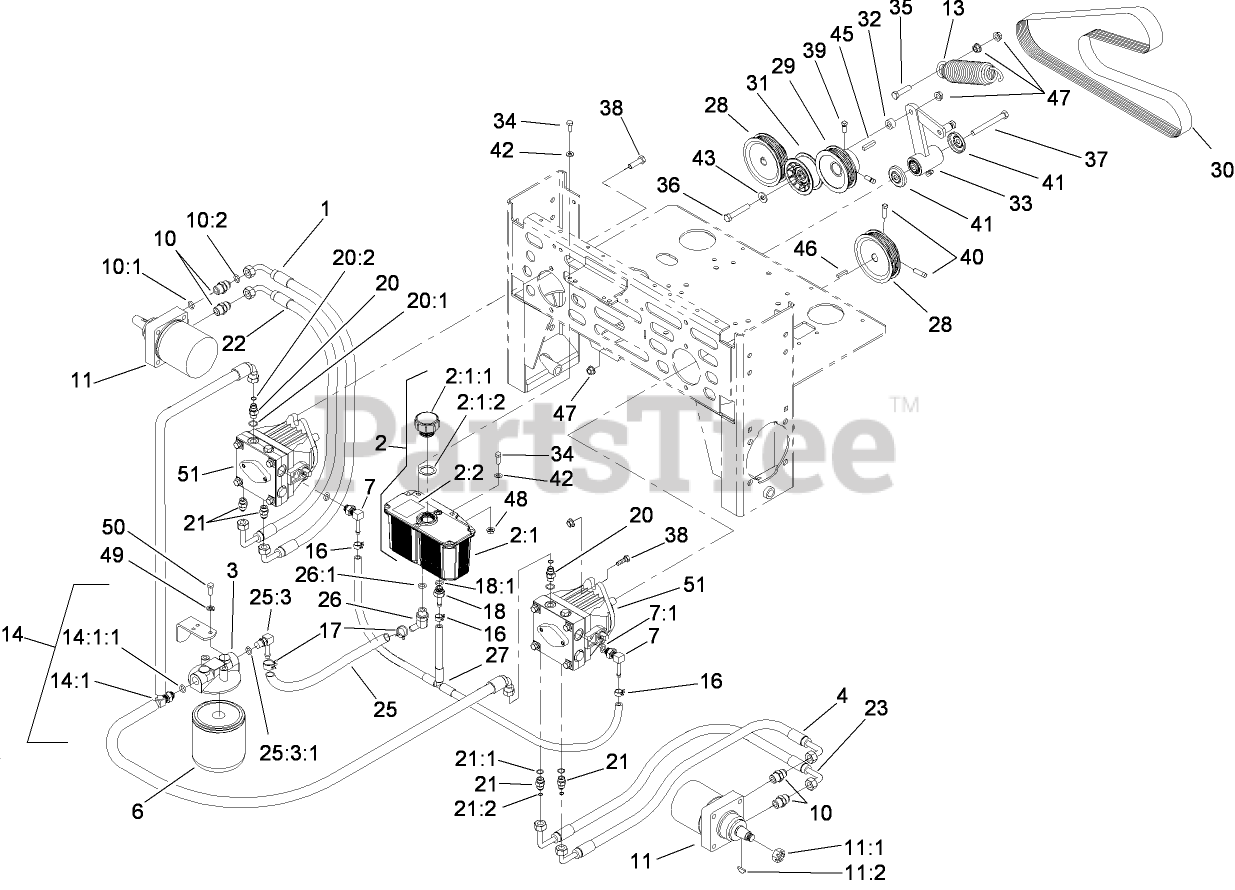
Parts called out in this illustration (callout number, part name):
1	HYD HOSE ASM
2	HYD Reservoir ASM
2:1	Reservoir-HYD
2:1:1	CAP-RESERVOIR, HYD
2:1:2	GASKET-CAP
2:2	DECAL-TANK, HYD
3	HEAD-FILTER
4	HYD HOSE ASM
6	FILTER-OIL, HYD (WINTER)
6	FILTER-OIL, HYD
7	ELBOW-90 DEG
7:1	O-RING
10	Fitting-Straight
10:1	O-RING
10:2	O-Ring
11	MOTOR-WHEEL
11:1	NUT-HH
11:2	KEY-WOODRUFF
13	Spring-Extension
14	HYD HOSE ASM
14:1	ADAPTER-RUN, TEE
14:1:1	O-RING
16	Clamp-Hose
17	Clamp-Hose
18	Adapter-Straight
18:1	O-RING
20	FITTING-STRAIGHT
20:1	O-Ring
20:2	O-RING
21	FITTING-STRAIGHT
21:1	O-RING
21:2	O-Ring
22	HYD HOSE ASM
23	HYD HOSE ASM
25	HYD HOSE ASM
25:3	FITTING-BARB
25:3:1	O-RING
26	FITTING-BARBED, 45 DEG
26:1	O-RING
27	HYD Hose ASM
28	SHEAVE
29	SHEAVE
31	PULLEY-FLAT IDLER
32	SPACER
33	PUMP IDLER ASM
34	SCREW-HH
35	SCREW-HH
36	SCREW-HH
37	SCREW-HH
38	SCREW-HH
39	SCREW-SET
40	SCREW-SET
41	GUARD-TOP
42	WASHER-FLAT
43	WASHER-FLAT
45	KEY-SQUARE
46	KEY-SQUARE
47	NUT-HHF, WHIZ
48	NUT-HF
49	WASHER-LOCK
50	SCREW-HH
51	PUMP-HYD
